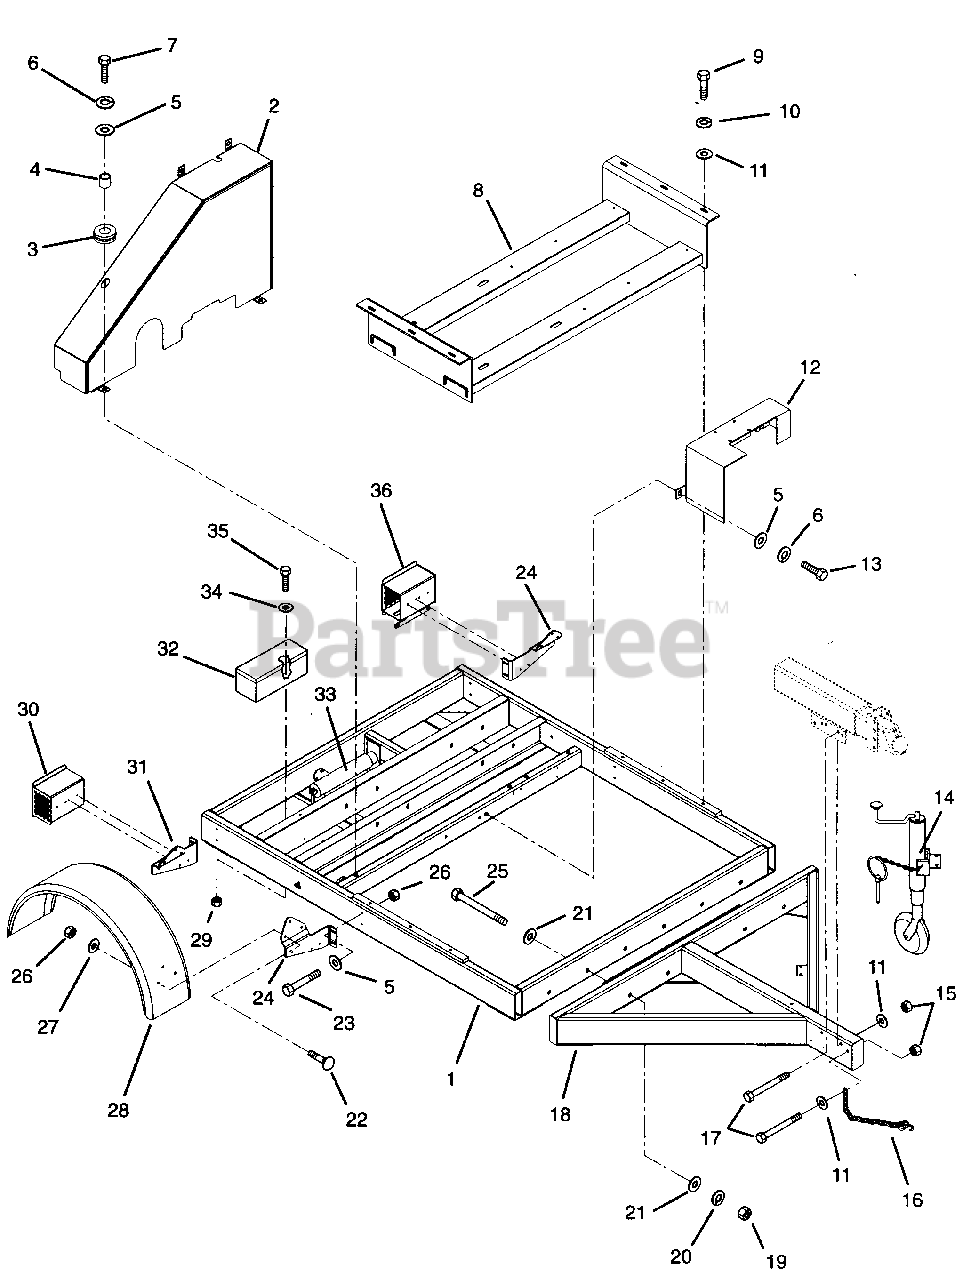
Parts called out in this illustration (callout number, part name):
1	Frame, Weldment
2	Weldment- Belt- Guard
3	Grommet .188 x .500
5	Washer - Flat - Steel .38 x .875 x .083
6	Washer - Lock .375 x 155
7	Bolt - Hex .38-16 x 100
8	Engine Base Weldment
9	Bolt - Hex .50 x 1.25 Grade 5
10	Washer - Lock .50 Reg.
11	Washer - Flat - Steel .563 x 1.375 x .109
12	Hydraulic Component Cover Weldment
13	Bolt-Hex .38-16 x .75 Grade 5
14	Jack/Wheel
15	Nut - Locking - Crown .50-13
16	Safety Chain
17	Bolt-Hex .50-13 x 5.00 Grade 8
18	Drawbar Weldment
19	Nut .75-10
20	Washer - Lock .750 x .188
21	Washer - Flat - Steel .313
22	Bolt - Round Head Square Neck .31-18 x 1.0
23	Bolt - Hex .31-18 x 3.00 Grade 2
24	Fender Bracket - Left Hand
25	Bolt - Hex .75-10 x 5.50
26	Nut - Locking .312-18
27	Washer - Flat - Steel .38 x 1.50 x 1.25
28	Fender
29	Nut .250-20
30	Tail Light Bracket Weldment
31	Fender Bracket Right Hand
32	Tool Box
34	Washer - Flat - Steel .312 x .734 x .065
35	Bolt - Hex .25-20 x .75 Grade 5
36	Left Hand Tail Light Bracket Weldment
